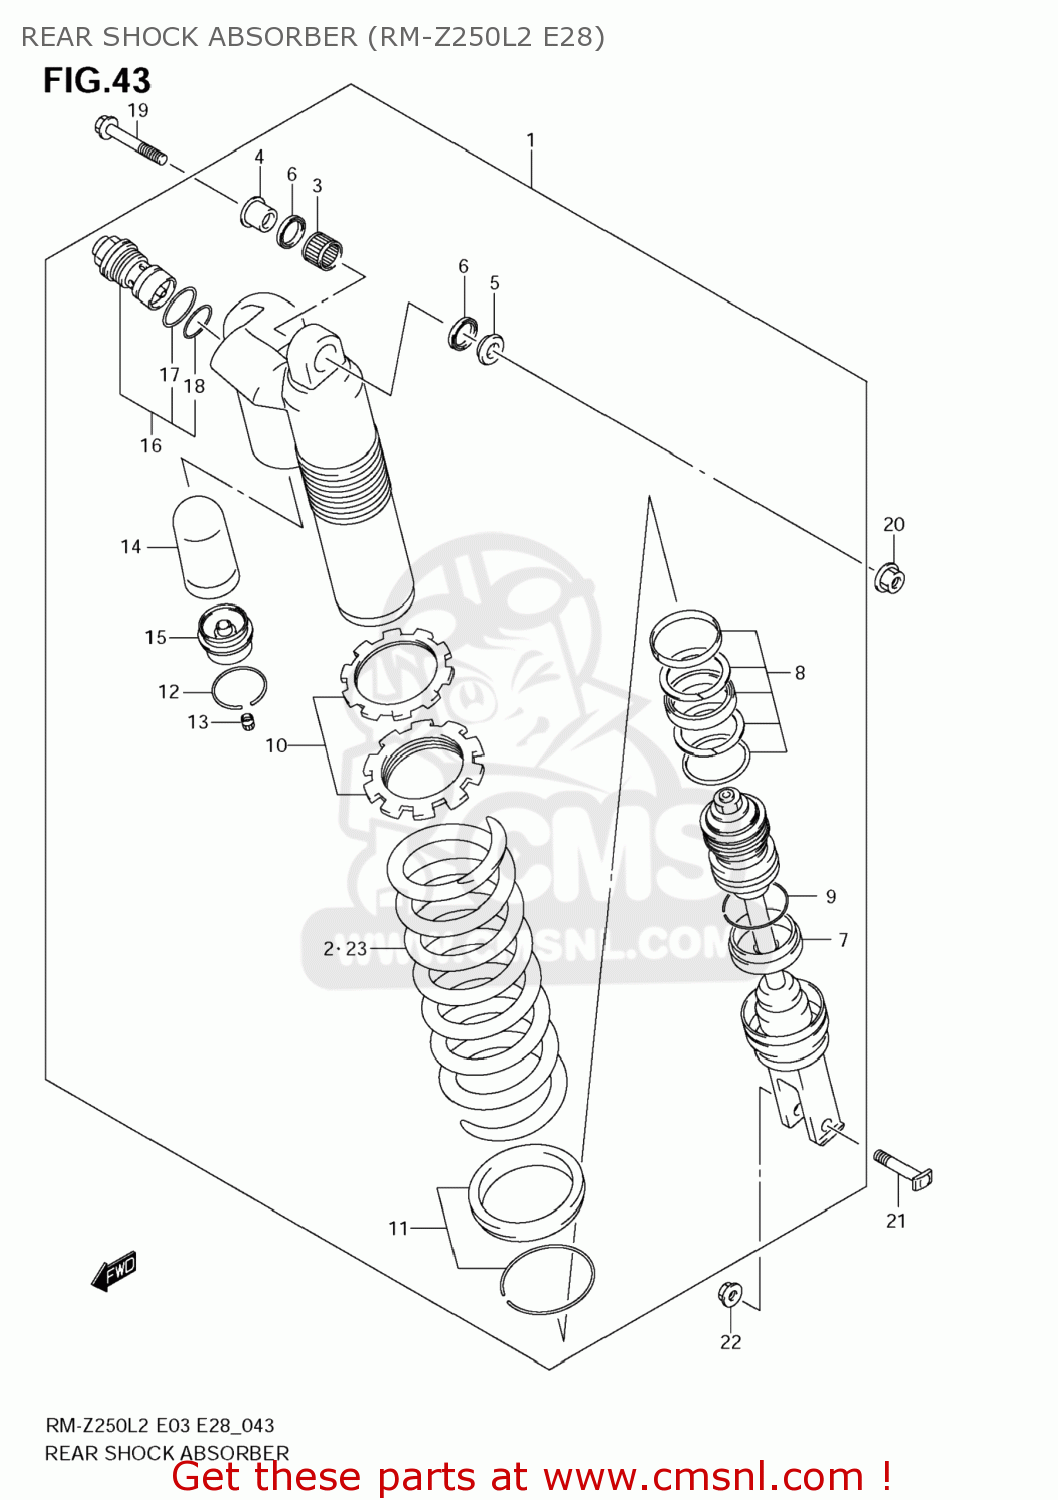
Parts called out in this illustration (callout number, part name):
1	ABSORBER ASSY,RR SHOCK
2	SPRING(K:5.7)
3	BEARING(16X22X12)
4	SPACER,UPPER BRG,R
5	SPACER,UPPER BRG,L
6	SEAL,OIL(16X22X2.5)
7	ROD,PISTON
8	O RING SET
9	RING,STOPPER
10	ADJUSTER SET
11	SPRING SEAT SET
12	RING,STOPPER
13	CAP,AIR VALVE
14	BLADDER
15	CAP,CHAMBER
16	BOLT,PLUG
17	O RING
18	O RING
19	BOLT,RR SHOCK ABSORBER UPR
20	NUT
21	BOLT,RR SHOCK ABSORBER LWR
22	NUT
23	SPRING(K:5.9)
